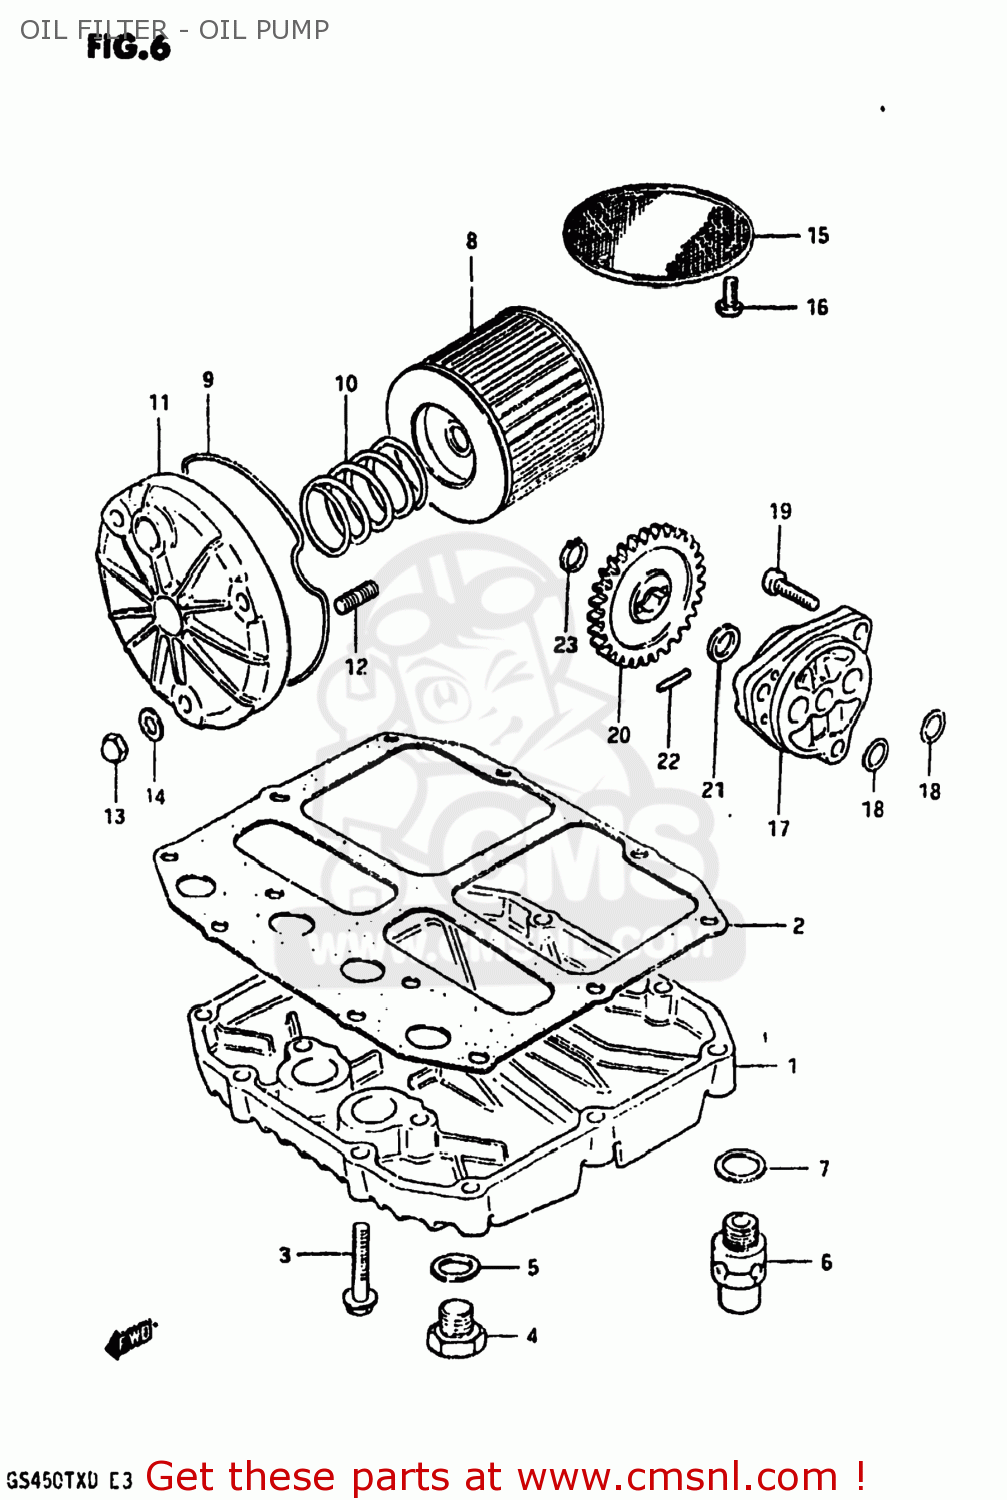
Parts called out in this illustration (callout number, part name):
1	PAN,OIL
2	GASKET,OIL PAN (MCA)
3	BOLT
4	PLUG
5	GASKET(14X19.2X2) (NAS)
6	REGULATOR ASSEMBLY,ENGINE
7	WASHER
8	FILTER ASSY,ENGINE OIL
9	O RING,OIL FILTER CHAMBER CAP
10	SPRING
11	CAP,OIL FILTER
12	STUD 6X20
13	NUT
14	WASHER
15	STRAINER,ENGINE OIL
16	SCREW 6X12
17	PUMP ASSY,ENGINE OIL
18	O RING(D:1.9,ID:13)
19	SCREW
20	GEAR,OIL PUMP DRIVEN
21	SHIM
22	PIN(4X15.8)
23	CIRCLIP
